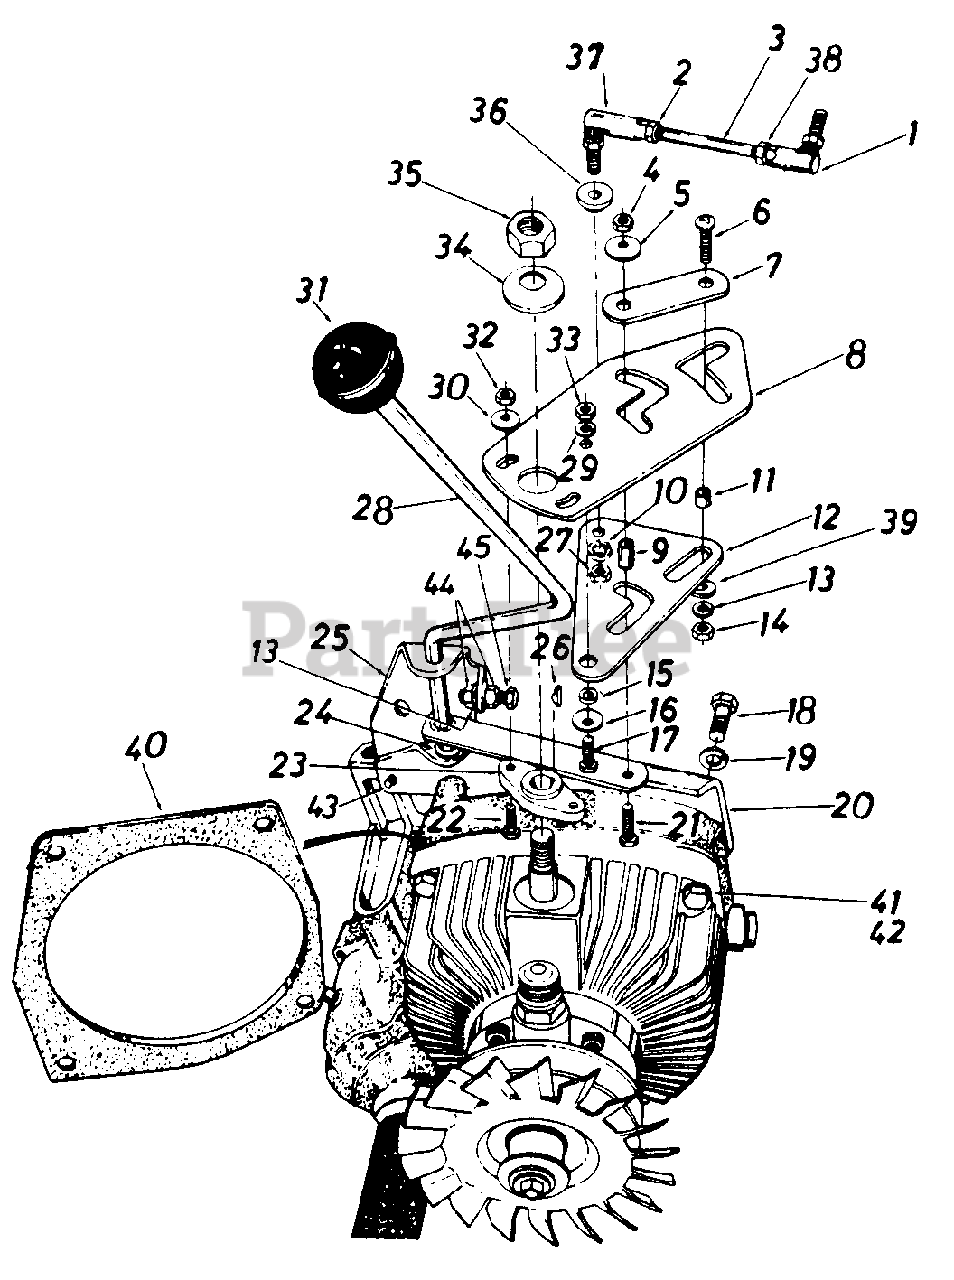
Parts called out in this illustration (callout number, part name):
1	Ball Joint Ass'y. 3/8-24 Thd.
2	Hex Nut 3/8-24 Thd. (L.H. Threads)
3	Control Rod 3/8-24 x 3.75"
4	Hex Nut 3/8-24 Thd.
5	Fl-Wash. .385" I.D. x .87"
6	Truss Mach. Scr. Phil. 5/16-18 x 1.00" Lg.
7	Locking Link
8	Pintle Main Control Plate
9	Spacer.83" Lg.
10	L-Wash. 3/8" I.D.
11	Spacer.35" Lg.
12	Pintle Drive Plate
13	L-Wash. 5/16" I.D.
14	Hex Nut 5/16-18 Thd.
15	Spacer 38" l.D. x .227" Lg.
16	Fl-Wash. .385" I.D. x .87"
17	Hex Bolt 3/8-24 x 1.00" Lg.
18	Hex Bolt 3/8-16 x 1.0" Lg.(Grade 5)
19	L-Wash. 3/8" I.D.
20	Shift Lever Bracket
21	Hex Bolt 3/8-24 x 1.25" Lg.
22	Hex Bolt 1/4-28 x .75" Lg.
23	Pintle Hub
24	Nyliner.375" Dia. x .140
25	Shift Lever Bracket-Upper
26	#5 Hi-Pro Key 1/8 x 5/8 Dia.
27	Hex Nut 3/8-24 Thd.
28	Shift Lever Ass'y.
29	L-Wash. 3/8" l.D.
30	Fl-Wash. 385" l.D. x .87"
31	Gear Shift Knob
32	Hex Nut 1/4-28 Thd.
33	Hex Nut 3/8-24 Thd.
34	Bell-Wash. 505" l.D. x 1.00"
35	Hex Nut 1/2-13 Thd.
36	Shld. Spacer .625" l.D.
37	Ball Joint Ass'y. 3/8-24 L.H. Thd.
38	Hex Jam Nut 3/8-24 Thd.
39	Fl-Wash. .330" I.D. x 1.25"
40	Gasket
41	Hex Bolt 3/8-16 x 2.75" Lg. (Grade 5)
42	Fl-Wash. .385" I.D. x .62"
43	Hex Wash. Hd. Self-Tap Scr. l/4-20 x .50" Lg.
44	Hex Nut 5/16-24 Thd.
45	Hex Bolt 5/16-24 x 1.0" Lg.
